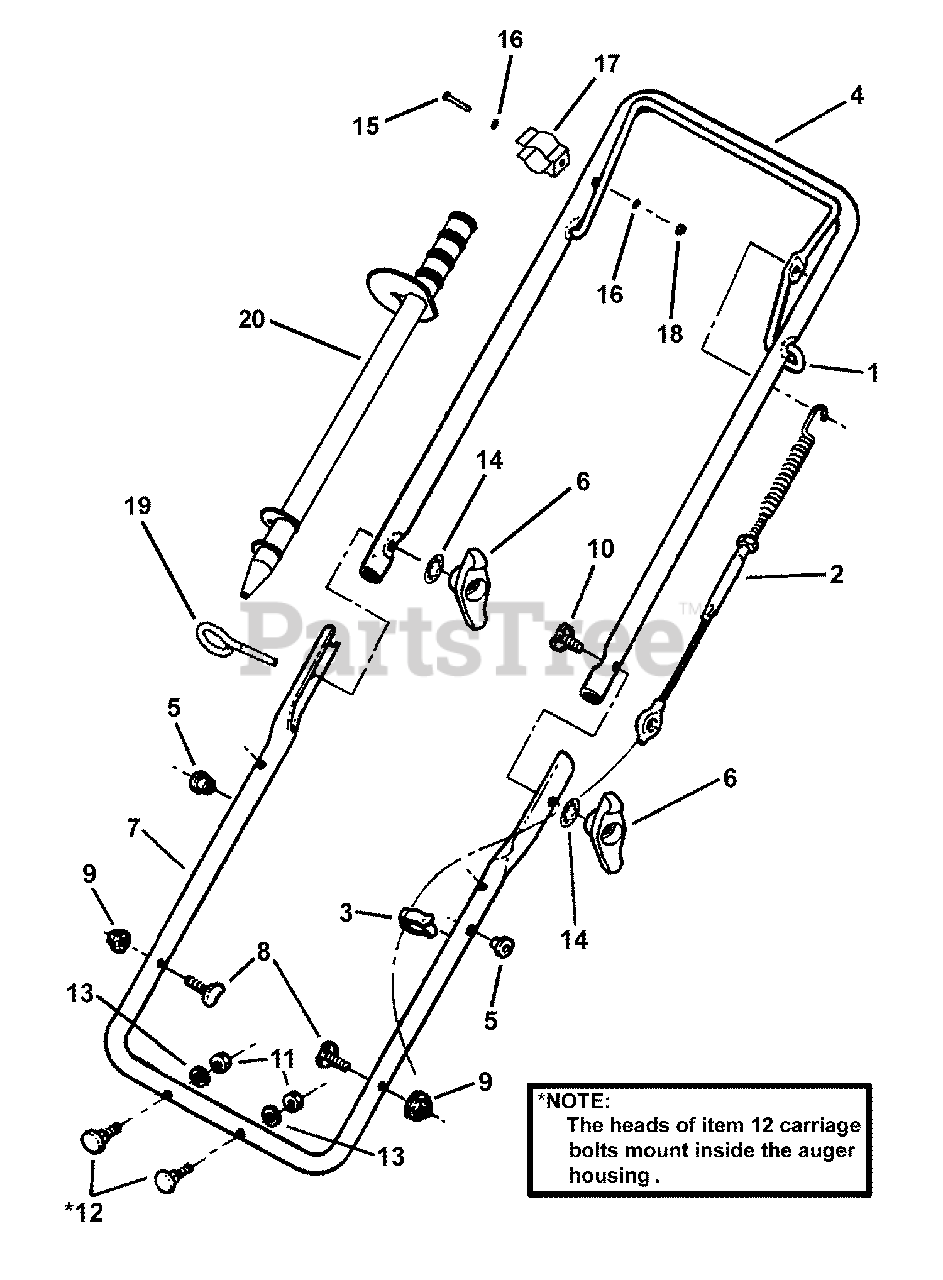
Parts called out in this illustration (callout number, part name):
1	BAIL, Drive Control
2	CABLE, Drive Control
3	CLIP, Wiring Harness
4	HANDLE, Upper
5	INSERT, Nylon
6	KNOB, 5/16-18 Wing (Black)
7	HANDLE, Lower
8	BOLT, 5/16-18 x 1-3/8" Curved Head
9	NUT, 5/16-18 Hex Flange Lock, GR 5
10	BOLT, 5/16-18 x 2" Curved Head, GR 2
11	NUT, 5/16-18 Hex
12	* BOLT, 5/16-18 x 1-1/2" Square Neck Carriage, GR 5
13	WASHER, 5/16" Split Lock
14	WASHER, 5/16" Internal Tooth Lock
15	SCREW, #10-24 x 1-1/4" Hex Head Cap, GR 5
16	WASHER, #10 Flat
17	HOLDER, Snostik, Upper
18	NUT, #10-24 Hex Center Lock
19	HOLDER, Snostik, Lower (5/16-18 thread)
20	SNOW STICK
